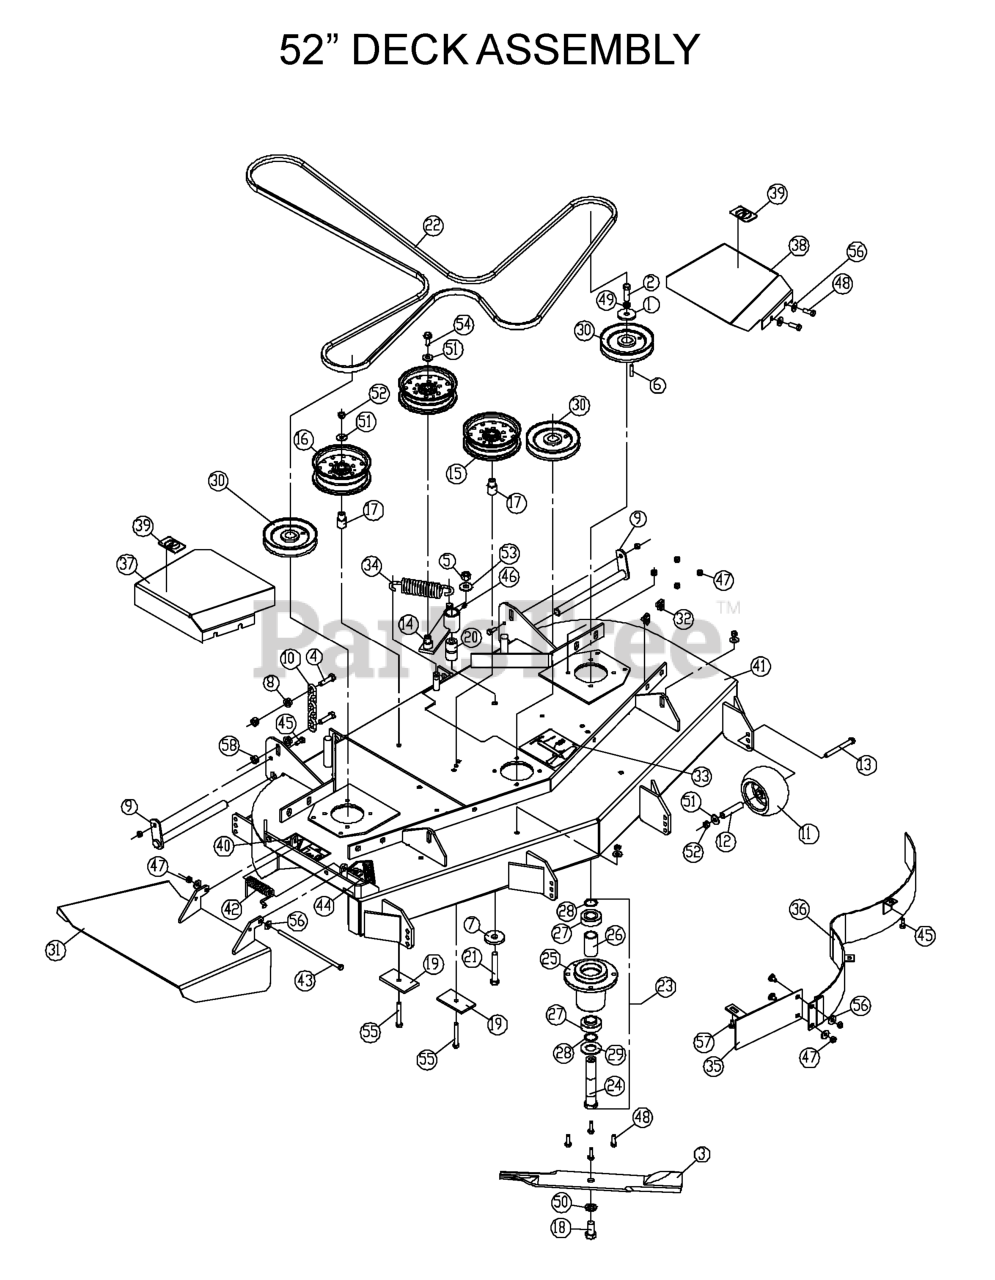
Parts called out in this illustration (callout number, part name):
1	SPINDLE WASHER
2	HCS 7/16F X 1 1/2
3	BLADE OEM 18"
4	HCS 7/16C X 1 1/2
5	NUT 1/2-13 HEX NYLOC ZD
6	KEY 1/4 SQ X 1 1/8
7	WASHER, SUPPORT
8	NUT 7/16C WHIZ
10	LIFT CHAIN
11	ANTI-SCALP ROLLER
13	HCS 3/8C X 3 1/2
15	IDLER PULLEY
16	IDLER PULLEY (TALL)
17	IDLER BUSHING
18	HCS 5/8F X 1 1/4
19	SUPPORT PLATE
20	PIVOT BUSHING
21	HCS 1/2C X 3 1/4
22	BELT, DECK
23	HOUSING ASM.
25	HOUSING, DIE CAST
27	BEARING
28	BUSHING.MACHINE.18.GAUGE
29	MACHINERY BUSHING 10 GA.
30	PULLEY 52" DECK
31	DISCHARGE CHUTE
32	U-CLIP 5/16-18 NUT RETAINER
33	DECAL, BELT ROUTING
34	DECK SPRING
35	CENTER BAFFLE - 52"
36	MAIN BAFFLE 52"
37	SHIELD, BELT 52" RT
38	SHIELD, BELT 52" LT
39	DECAL, NO STEP
40	DECAL, EURO SEVERING
41	52 CE DECK WITH DECALS
42	SPRING, TORTION
43	HCS 5/16-18 X 8-1/2 GR 5 ZD
44	DECAL, CPSC
45	HCS 5/16C X 3/4
46	ZERK
47	NUT 5/16C CENTERLOCK
48	HCS 5/16C X 1
49	WASHER 7/16 LOCK
50	LOCKWASHER 5/8
51	WASHER 3/8 FLAT
52	NUT 3/8C CENTERBLOCK
53	WASHER 1/2 FLAT
54	4CS 3/8C X 1 SERRATED HEAD
55	HCS 3/8C X 2 1/2
56	WASHER 5/16 FLAT
57	CARRIAGE BOLT 5/16C X 5/8"
58	NUT 7/16C CENTERLOCK
